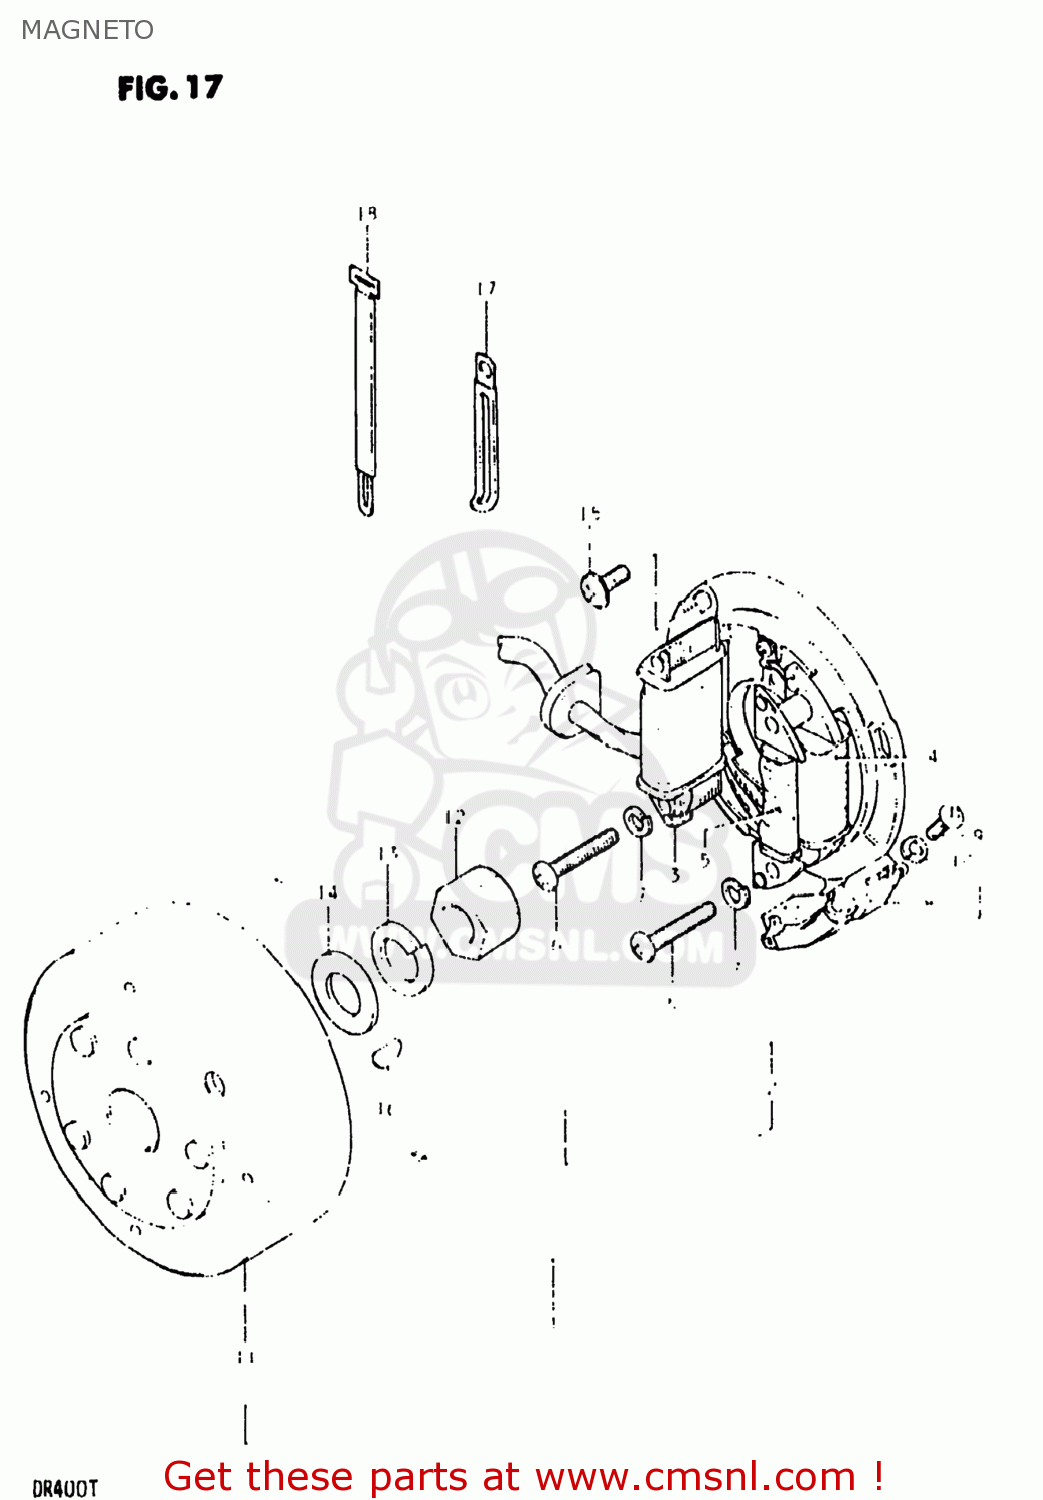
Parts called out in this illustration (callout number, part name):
1	MAGNETO ASSEMBLY
2	STATOR ASSEMBLY
3	COIL,LIGHTING
4	COIL,PRIMARY
5	COIL,PULSER
6	SCREW
7	LOCK WASHER
8	COIL,PULSER
9	SCREW
10	LOCK WASHER
11	ROTOR ASSEMBLY
12	NUT
13	LOCK WASHER
14	WASHER(14X27X3)
15	SCREW(5X14)
16	KEY 4MM
17	CLAMP
18	CLAMP
